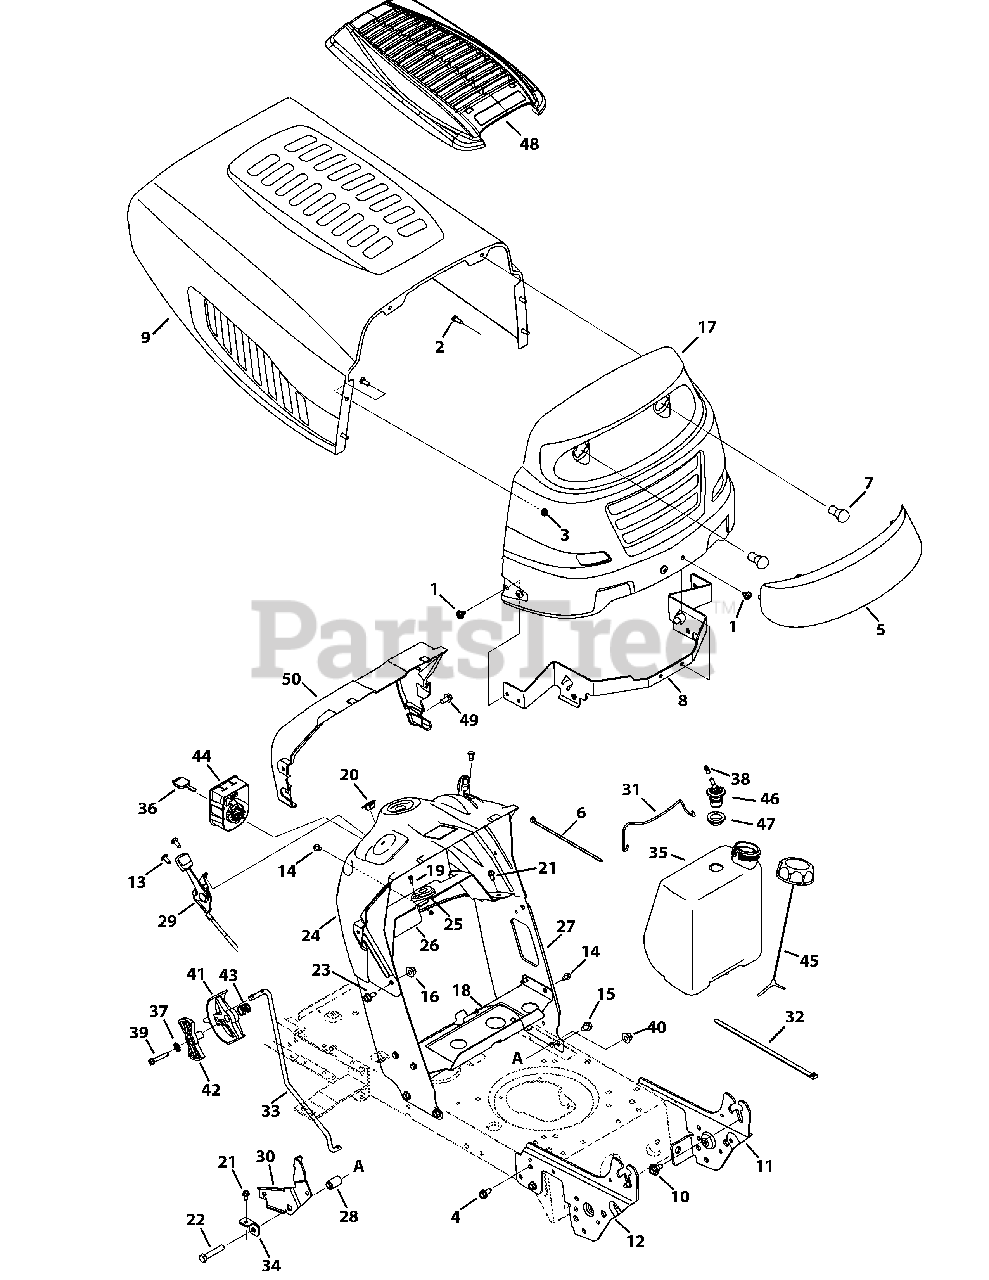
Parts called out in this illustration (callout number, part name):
1	Screw, 5/16-18 x .375
2	Hex Screw, 1/4-20 x .620
3	Flangelock Nut, 1/4-20
4	Screw, 5/16-18 x .750
5	Grill Lens
6	Cable Tie
8	Hood Pivot Bracket
9	Hood - Red
10	Shoulder Screw, 5/16-18 x .43 x .29
11	Left Support Pivot Bracket
12	Right Support Pivot Bracket
13	Screw, 1/4-20 x .500
14	Screw, 1/4-20 x .500
15	Screw, 5/16-18 x .625
16	Flangelock Nut, 5/16-18
17	Grill
18	Gas Tank Support Bracket
19	Screw, #10-16 x .500
20	Choke Plug
21	Tap Screw, 1/4-20, 0.625
22	Hex Screw, 3/8-16 x 2.0
23	Hex Screw, 5/16-18 x .625
24	Dash, Upper
24	Dash, Upper No RMC
25	Bearing, .628 ID x 1.36
27	Dash, Lower
28	Flange Spacer, .390 x .671 x 1.095
29	Throttle/Choke Cable
31	Battery Assembly Rod
32	Cable Tie
33	Speed Control Rod
34	Speed Latch Tab
35	1.36 Gallon Fuel Tank
37	Lock Washer, 1/4
38	Hose Vent, 3/16 EPA
39	Hex Washer Screw, 1/4-20 x 1.50
40	Flangelock Nut, 3/8-16
41	Shift Lever
42	Index Control
43	Compr. Spring, .72 OD x .78
44	3 Position Key Switch
45	Fuel Cap, 2.25"
46	Rollover Valve
47	Rubber Grommet, 23 x 3.55
48	Hood Scoop
49	Screw, 1/4-15 x .750
50	Dash Collar
